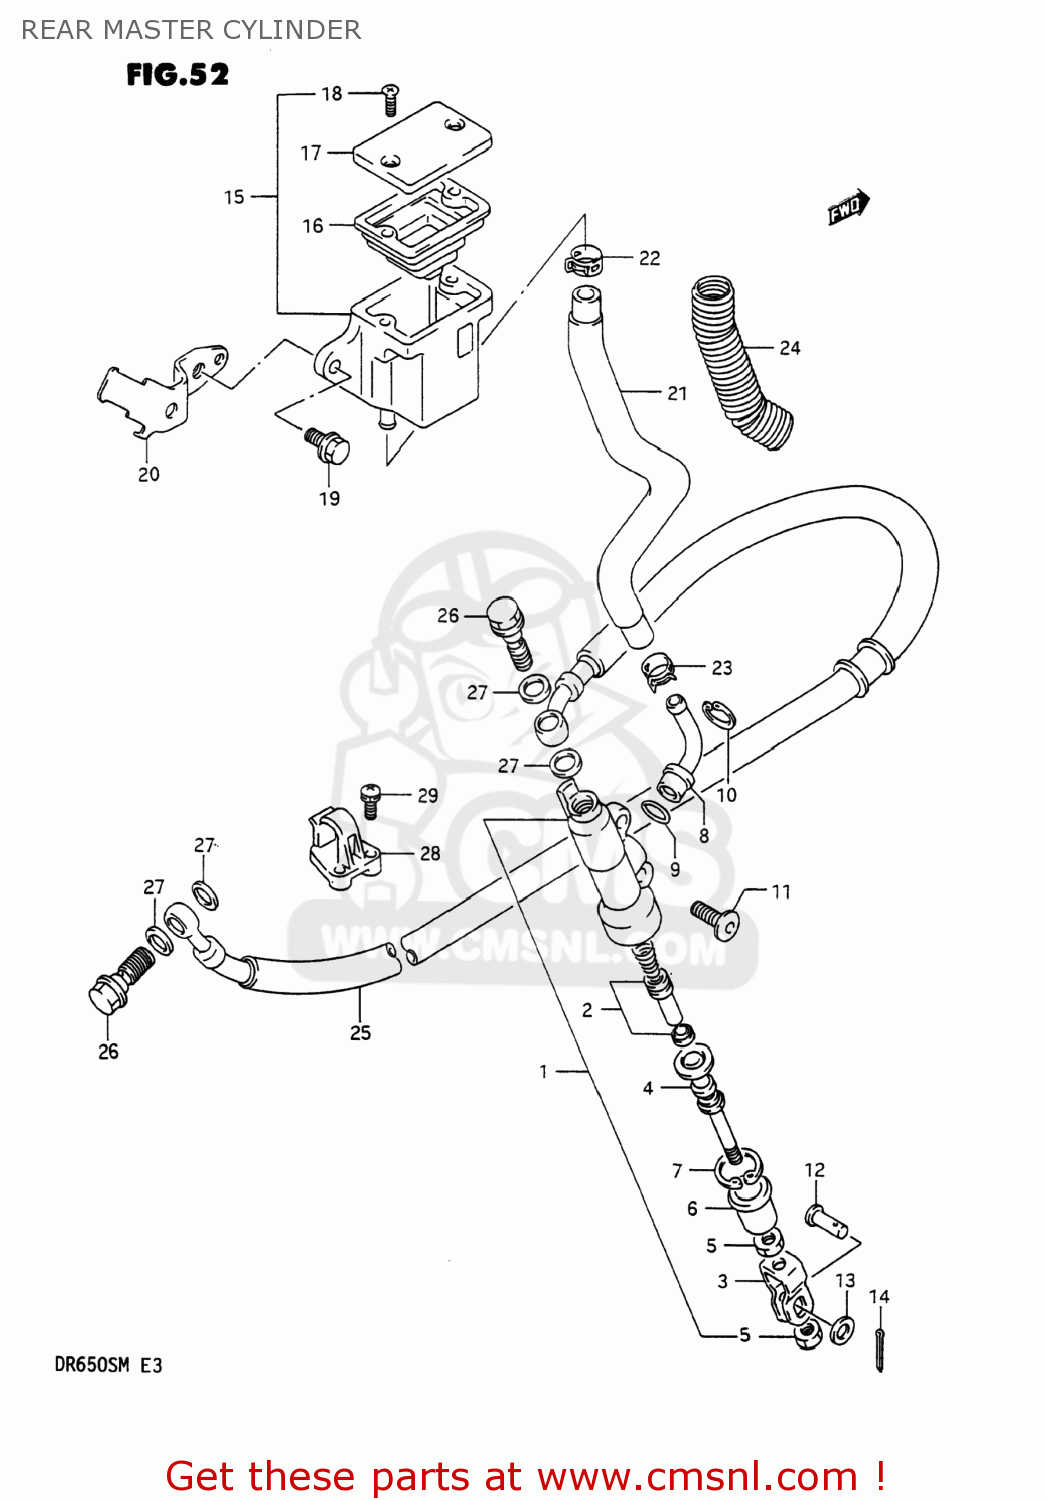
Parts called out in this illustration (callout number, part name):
1	CYLINDER ASSY,RR MASTER
2	PISTON/CUP SET
3	YOKE
4	ROD,PUSH
5	NUT
6	BOOT
7	CIRCLIP
8	CONNECTOR
9	O RING
10	CIRCLIP
11	BOLT(6X18)
12	PIN
13	WASHER
14	PIN
15	TANK ASSEMBLY,RESERVOIR
16	DIAPHRAGM
17	CAP
18	SCREW
19	BOLT
20	PLATE COMP,RESERVOIR T
21	HOSE COMP,RESERVOIR TANK
22	CLIP
23	CLAMP
24	SHIELD,RESERVOIR TANK HOSE
25	HOSE COMP,REAR BRAKE
26	BOLT UNION
27	WASHER(10X15X1.5)
28	GUIDE,RR BRAKE HOSE
29	SCREW
